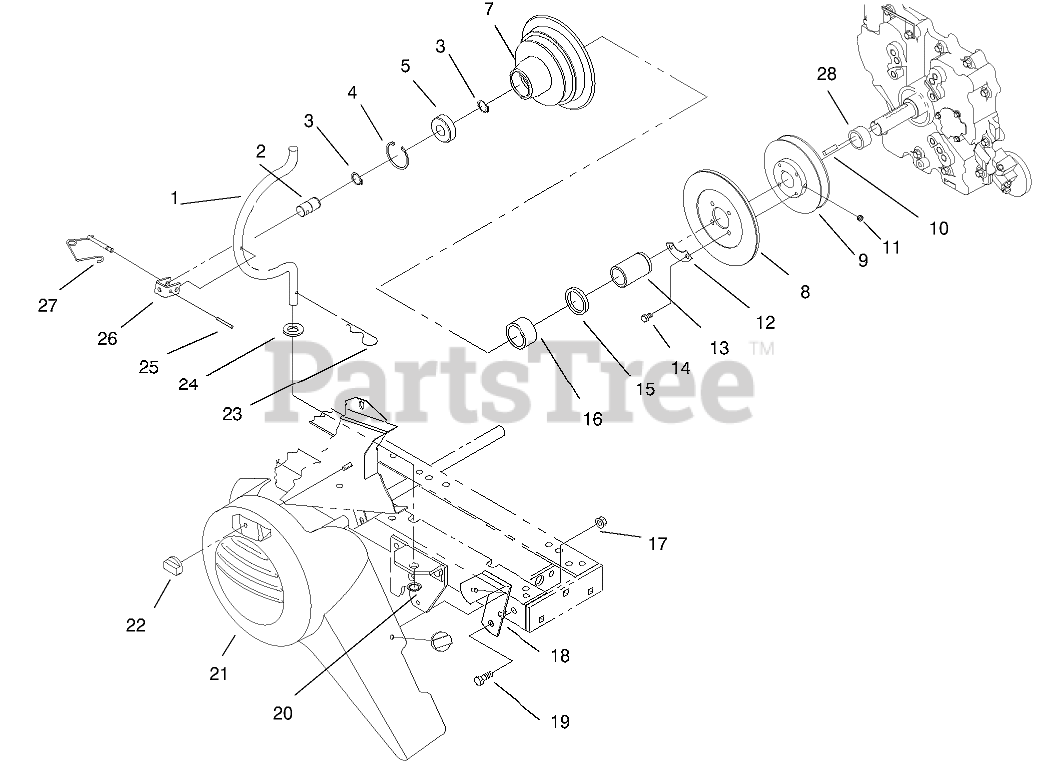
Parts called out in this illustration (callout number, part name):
1	ROD-HOUSING
2	SHAFT-PTO
3	Ring-Snap
4	RING-RETAINING
5	BEARING-BALL
7	Housing-Clutch
8	ASS'Y-CLUTCH PLATE
9	PULLEY
11	SCREW-SET, HSH
12	RETAINER
13	RACE-BEARING
14	SCREW-HEX HD CAP
15	SEAL-OIL
16	Seal
17	NUT-FLANGE
18	BELT COVER BRKT ASM
19	SCREW-HH
20	RING-REINFORCED CIRC
21	GUARD - BELT
22	NUT - WING
23	PIN-COTTER, HAIR
24	WASHER-FLAT
26	CLEVIS
27	LOCKING PIN ASM
28	SPACER-CRANKSHAFT
